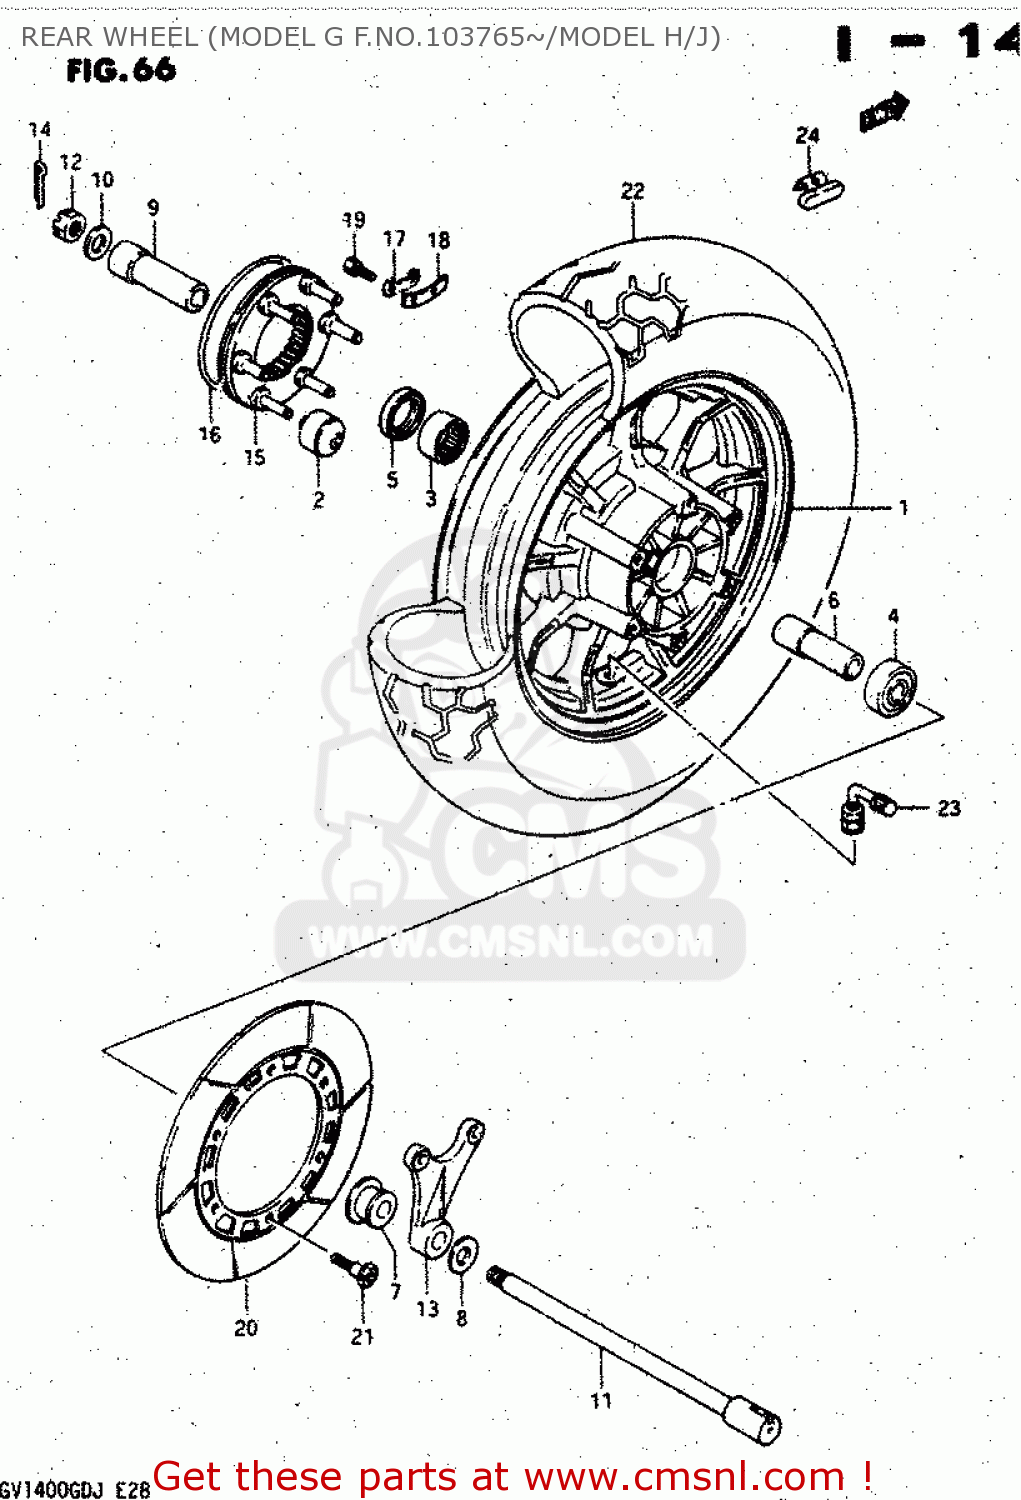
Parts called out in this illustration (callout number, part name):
1	WHEEL SET,REAR
2	BUSH
3	ROLLER BEARING (30X37X2
4	BEARING
5	SEAL,OIL(30X44X7)
6	SPACER,REAR HUB BEARING
7	SPACER COMP,REAR AXLE
8	WASHER,REAR AXLE,RIGHT
9	SPACER,REAR AXLE,LEFT
10	WASHER,HUB
11	AXLE,REAR
12	NUT 18MM
13	BRACKET,REAR CALIPER
14	PIN,COTTER
15	JOINT ASSY,RR HUB DRIVEN
16	O RING(D:2.1,ID:65)
17	WASHER
18	WASHER,THRUST(T:1.6)
19	BOLT(6X16)
20	DISC,REAR BRAKE
21	BOLT
22	TIRE
23	VALVE ASSY,WHEEL RIM(SA-1A)
24	BALANCER,WHEEL
